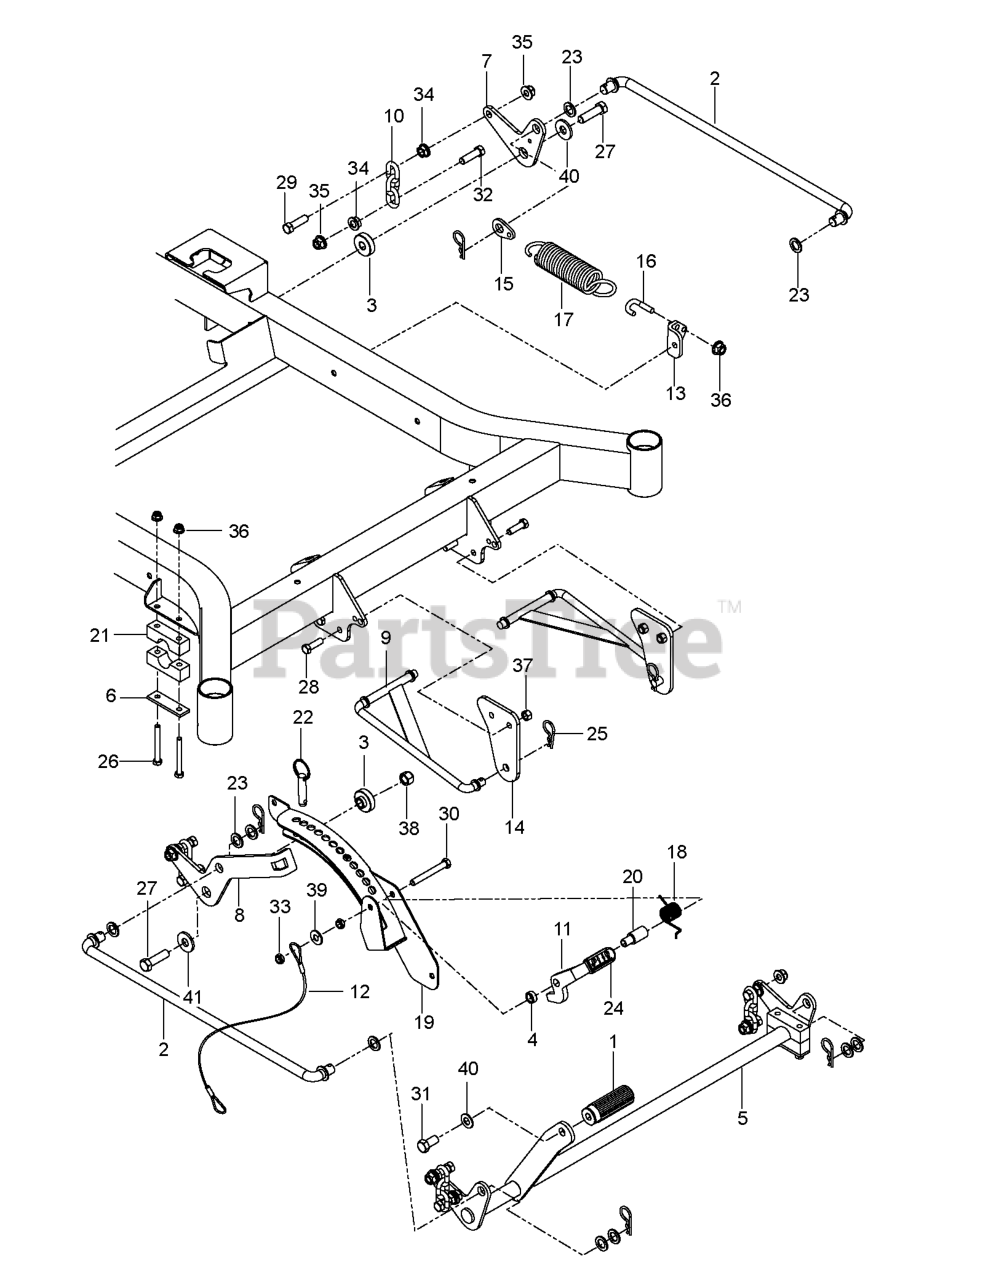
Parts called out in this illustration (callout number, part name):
1	PEDAL, DECK HEIGHT
2	CROSS LINK
3	SPACER.IDLER.METAL.POWDER
4	SPACER, .3
5	LIFT.PNT.MZ.DECK.WELD.E-DIP
6	REINFORCEMENT.PLATEX431
7	BELLCRANK, RR, LIFT
8	BELLCRANK, RR, RT
9	STRUT LINKAGE
10	LIFT CHAIN - 3 LINK
11	LATCH, TRANSPORT
13	MOUNT, SPRING
14	MOUNT, STRUT
15	TAB, SPRING
16	J-BOLT
18	SPRING, TORSION
19	HEIGHT, ADJUST, DECK
20	PIVOT, LATCH, TRANSPORT
21	PILLOW BLOCK
22	PIN, 1/2 X 1 1/2, DETENT RING
23	BUSHING
24	GRIP, TRANSPORT-RELEASE
25	PIN, COTTER 1 3/4
26	HCS 5/16C X 2-3/4
27	HCS 1/2-13 X 1 3/4 GR 8
28	HCS 3/8C X 1 1/4 GR5
29	HCS 7/16C X 1 1/2
30	BOLT.HEX.FIN.3/8-16 X 3.GR5
31	HHCS 1/2-13 X 1
32	HCS 7/16 - 14 X 1 3/4
33	NUT HEX 3/8-16 NYLON, THIN
34	NUT 7/16-14 HEX WHIZ LK
35	NUT 7/16C WHIZ
36	5/16-18 NYLOC FLANGE NUT
37	NUT 3/8-16 NYLOC
38	NUT 1/2-13 HEX NYLOC ZD
39	RP WASHER 3/8 FLAT
40	WASHER, 7/16 DISC SPRING
41	WASH USS FLAT 1/2
